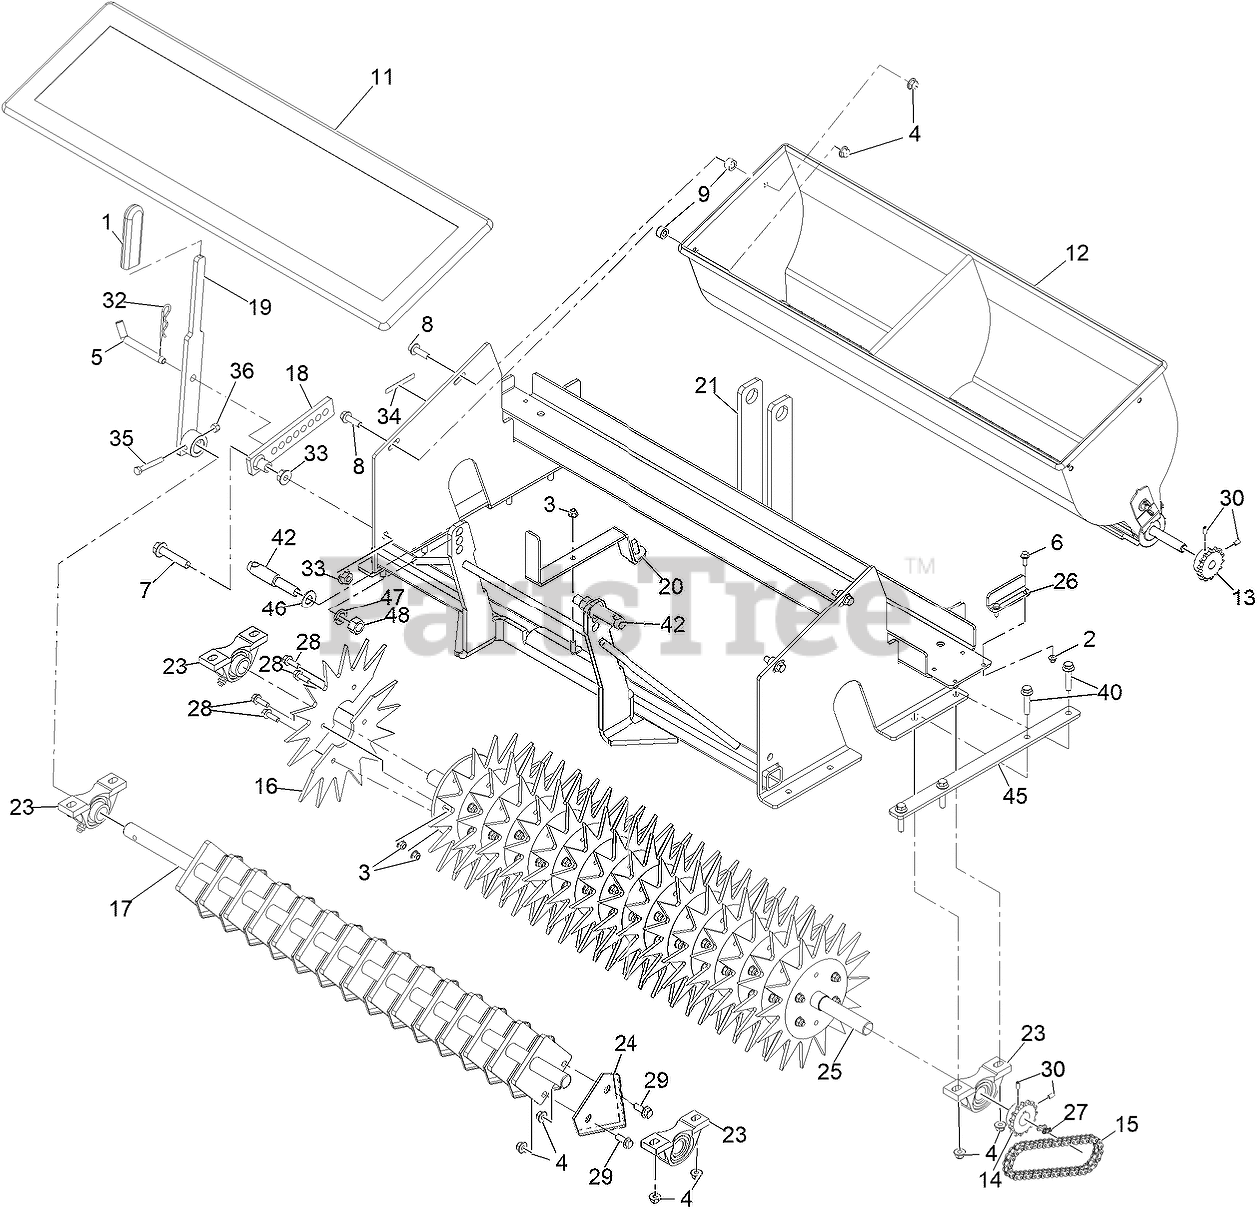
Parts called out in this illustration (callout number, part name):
1	GRIP-LEVER
3	NUT-HF, NI
4	NUT-HF, NI
5	1/2 X 4-3/4 BENT PIN
6	Screw-HHF
7	SCREW-HHF
8	SCREW-HHF
9	BUSHING-HOPPER
11	SLIT SEEDER DROP COVER
12	36" SLIT SEEDER HOPPER
13	SPROCKET-UPPER,SEEDER\NDA
14	SPROCKET-LOWER,SEEDER\NDA
15	Chain-Roller
16	Star, Slit Seeder
17	Shaft-Sq Plate [blk-Txt]
18	Arm-Ctrl, Seeder [blk-Txt]
19	Handle-Slit Seeder [blk-Txt]
20	Handle-Gate [blk-Txt]
21	FRAME-SEEDER, SLIT
23	PILLOW BLOCK BEARING
24	4' SLICING KNIFE\NR201313
25	DISC-SLIT SEEDER
26	Bracket-Weight [blk-Txt]
27	Link-Chain
28	SCREW-HHF
29	SCREW-HHF 3/8-16 X 1
30	Screw-Set, HSH
32	PIN-HAIR
33	NUT-HHF
34	DECAL-WARNING
35	SCREW-HH
36	NUT-LOCK, NI
40	SCREW-HHF
42	PIN-LIFT
45	PLATE-DOUBLER
46	WASHER-FLAT
47	WASHER-LOCK
48	NUT-HEX
